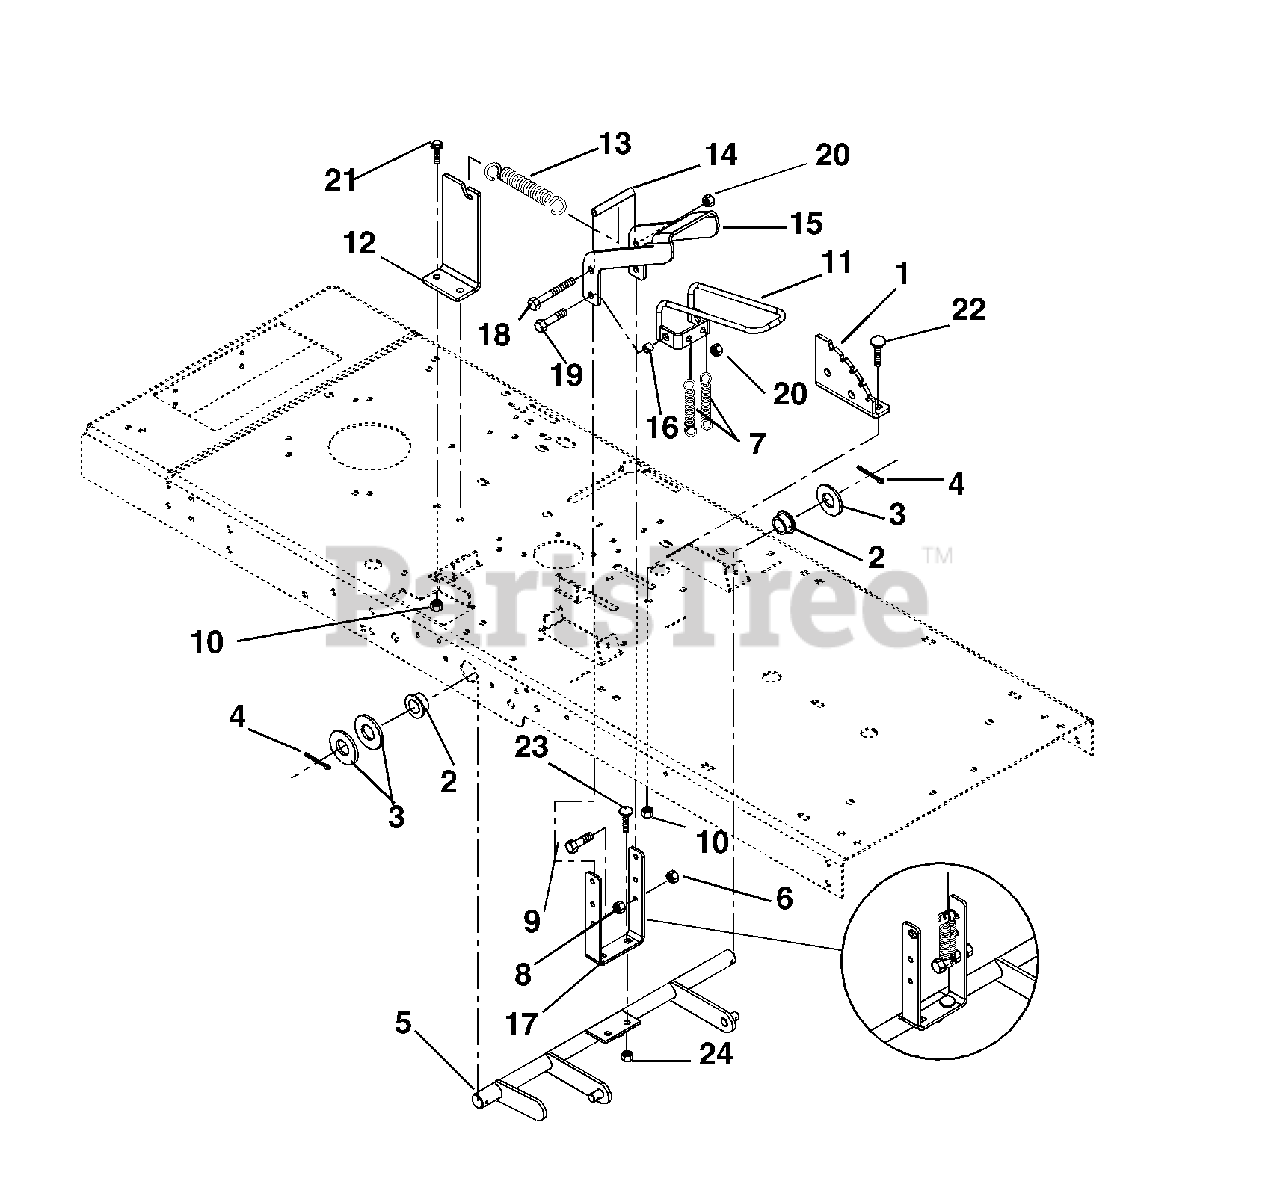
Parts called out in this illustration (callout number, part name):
1	DETENT, PLATE
2	BSHG-FLG1.020X1.385X.75X1.75NY
3	WSHR-FL-STL- 1.062X2.0X.134 YZ
4	@PIN-CTR .18X1.50 EXTPRSQCT YZ
5	LIFT, WLDM'T
6	@NUT-LK-CTR .25-20 YWZC
7	SG-TENS .092X.69X1.75 WLD 54
8	@NUT-HEX .25-20 YWZC
9	@BLT-HEX .25-20X2.00 GR5 YWZC
10	@NUT-LK-CTR .38-16 YWZC
11	RELEASE WLDM'T
12	BRACKET, LIFT
13	SG-TENS .187X1.50X9.94 WLD 40
14	SPACER .328 X .462 X 3.14
15	HANDLE, DECKLIFT
16	SPACER .328 X .462 X .410
17	BRACKET, HANDLE
18	@BLT-HEX .31-18X4.50 GR5 YWZC
19	@BLT-HEX .31-18X1.25 GR5 YWZC
20	@NUT-LK-NYL .312-18 YWZC
21	@BLT-HEX .38-16X1.00 GR5 YWZC
22	@BLT-RDHDSQNK .38-16X.75 G5YZ
23	@BLT-RDHDSQNK .38-16X1.00 G5YZ
24	@NUT-LK-TOP-FLG .38-16 YWZC
